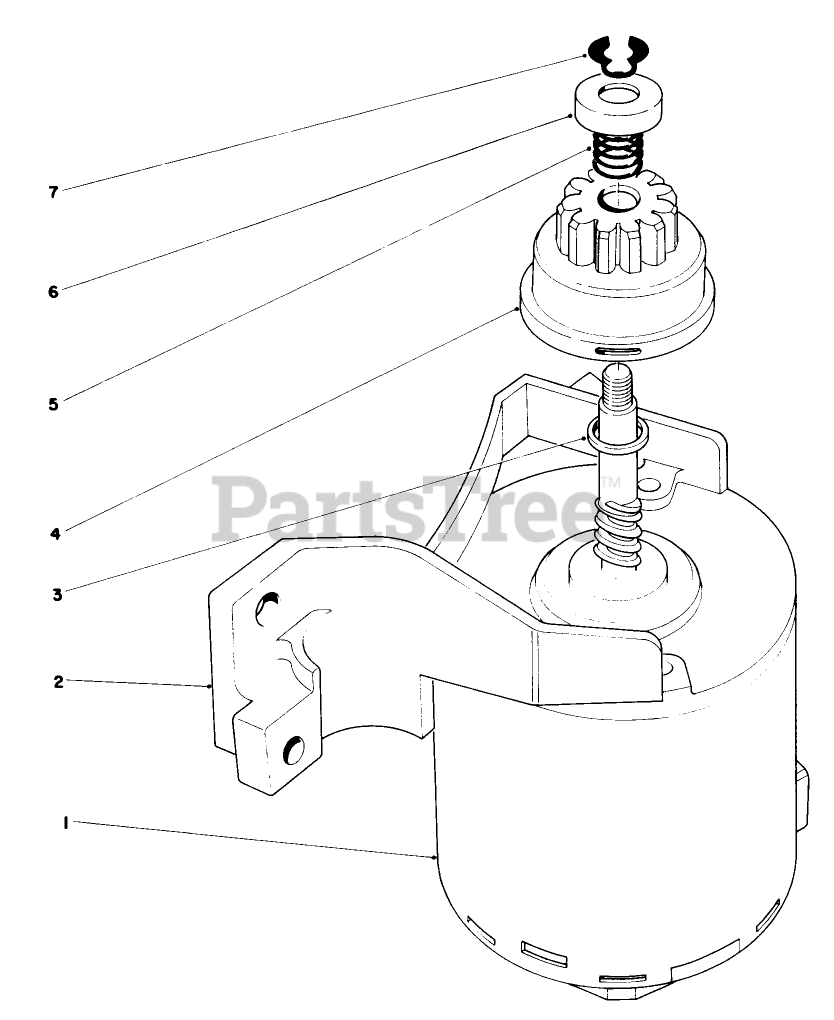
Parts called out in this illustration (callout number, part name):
1	END FRAME W/BRUSH
2	BRKT END FRAME
3	SPACER
4	Pinion Assembly
5	COMPRESSION SPRING
6	PINION STOP
7	Retaining Ring
